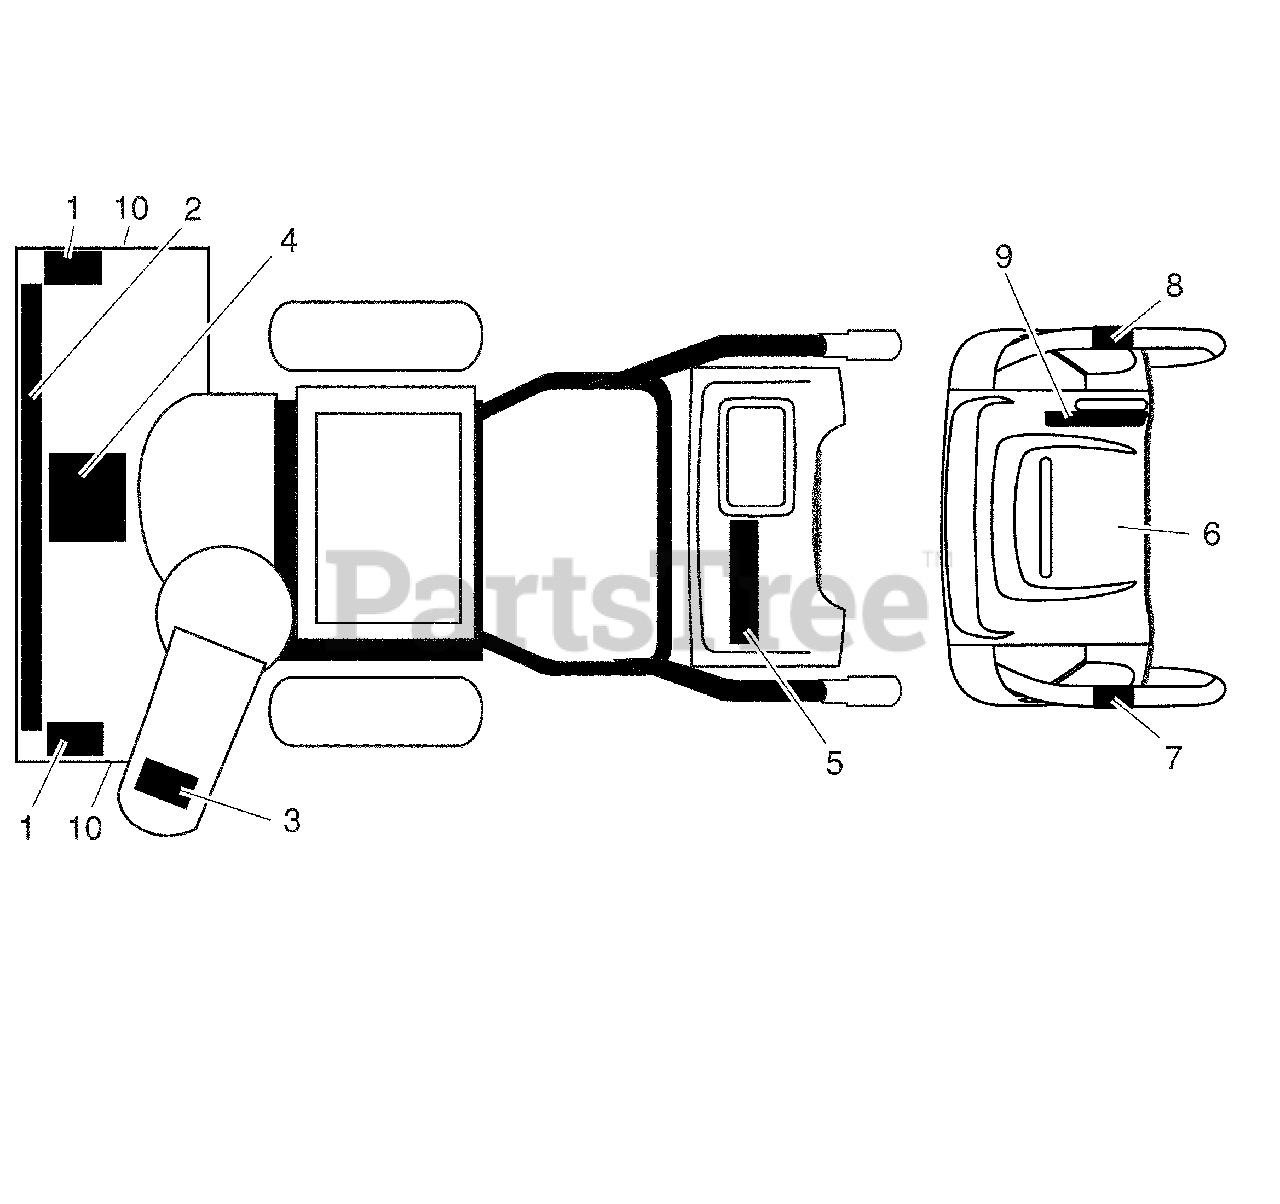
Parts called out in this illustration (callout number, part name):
1	Wheel Assembly, 16", LH
2	Pin, Klik 1/4
3	Wheel Assembly, 16", RH
4	Screw, Hex Head 5/16-18 x 5/8
5	Bearing, Axle
6	Washer, Thrust (1")
7	Screw, Hex Head 5/16-18 x 3/4
